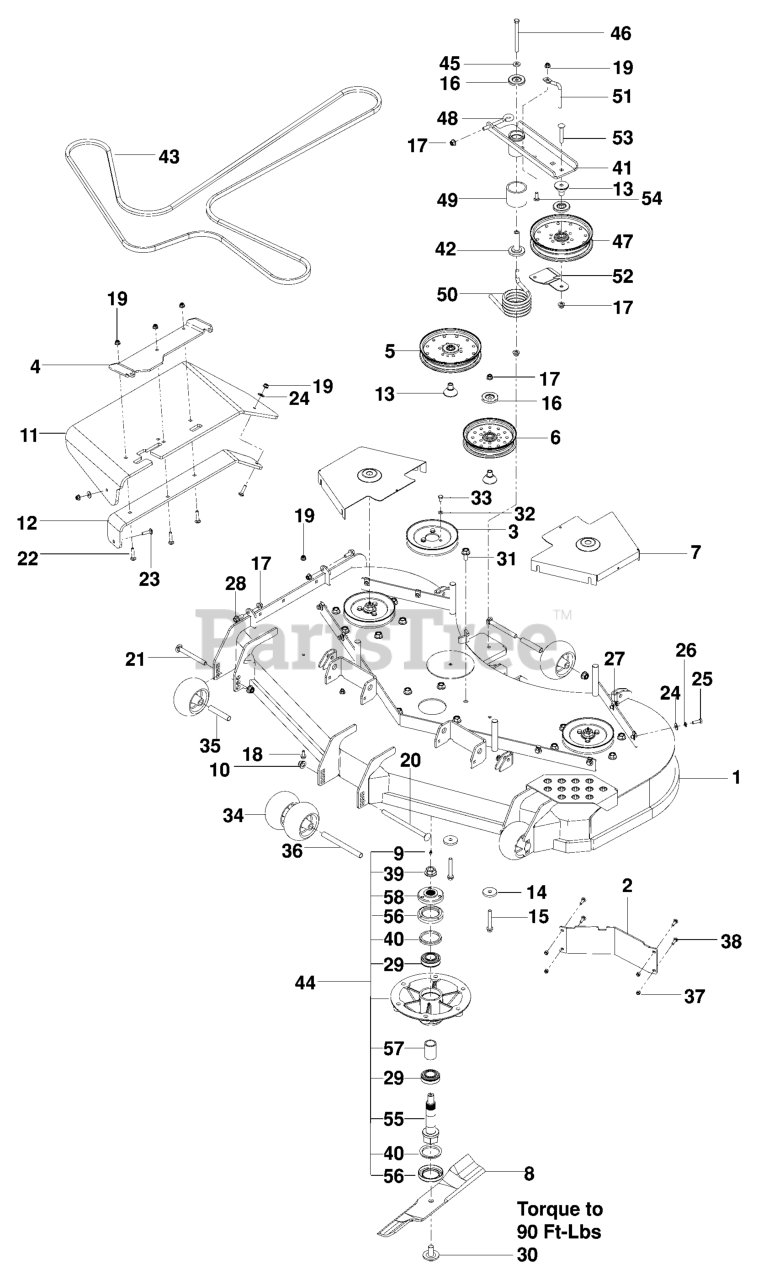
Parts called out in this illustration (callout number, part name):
1	DECK.SVC W/DECALS.60.ORANGE
2	BAFFLE, DIVERTER 54"/60" LH
3	PULLEY - 6.57
4	BRKT - CHUTE MTG BLACK
5	PULLEY - 7" NARROW
6	PULLEY IDLER, 6" NARROW
7	SHIELD,BELT, 60" ORANGE
8	BLADE - HEAVY DUTY 21"
9	ZERK
10	NUT, 1/2-13 HEX FLG NYLOC ZD
11	CHUTE, DISCHARGE 48-52
12	BRKT, CHUTE SUPPORT BLACK
13	BEARING, IDLER ARM
14	SPINDLE WASHER
15	HHFS 3/8-16 X 2 3/4
16	DUST SHIELD
17	NUT 3/8-16 HEX FLG NYLOC ZD
18	HHFS 5/16-18 X 3/4
19	5/16-18 NYLOC FLANGE NUT
20	RHSNB 1/2-13 X 8 GR5 ZD
21	RHSNB 1/2-13 X 4.75 GR5 ZD
22	RHSNB 5/16-18 X 1-1/2 GR 5 ZD
23	BOLT, CARRIAGE 5/16X1-1/4
24	WASHER 5/16 FLAT
25	HCS 5/16C X 1
26	WASHER.LOCK.HVY.HLCL.SPR.5/16
27	U-CLIP 5/16-18 NUT RETAINER
28	HHFS 3/8-16 X 1 GRD 5 ZD
29	BEARING - 206KRR8
30	BLADE BOLT/WASHER
31	HHFS 1/2-13 X 1 GR5 ZD
32	WASH 5/16 DISC SPRING ZD
33	HCS 5/16-18 X 1/2 GR 5 ZD
34	ROLLER, GAUGE .635 BORN
35	TUBE, ROLLER AXLE
36	TUBE, ROLLER AXLE LONG
37	NUT.1/4-20.HEX.NYLOC.ZD
38	RHSNB, 1/4-20 X 1, GR5
39	NUT FLANGE 3/4-16
40	V-RING, 55MM
41	ASSY, IDLER ARM, PZ
42	BEARING, IDLER PIVOT
43	BELT, "B", 176
44	SPINDLE ASM. 10"
45	WASHER, 3/8 THICK
46	HCS 3/8-16 X 4-1/2 GR 8 ZD
47	PULLEY - IDLER 7"
48	EYE BOLT, 3/8 X 4"
49	SPACER, IDLER PIVOT
50	SPRING, TORSION, IDLER
51	BELT KEEPER
52	BELT.GUIDE.BLACK
53	CARRIAGE BOLT 3/8-16 X
54	RHSSNB 5/16C X 1.0
55	SHAFT - SPINDLE
56	CUP - DEBRIS
57	SPACER - BEARING
58	HUB - PULLEY
